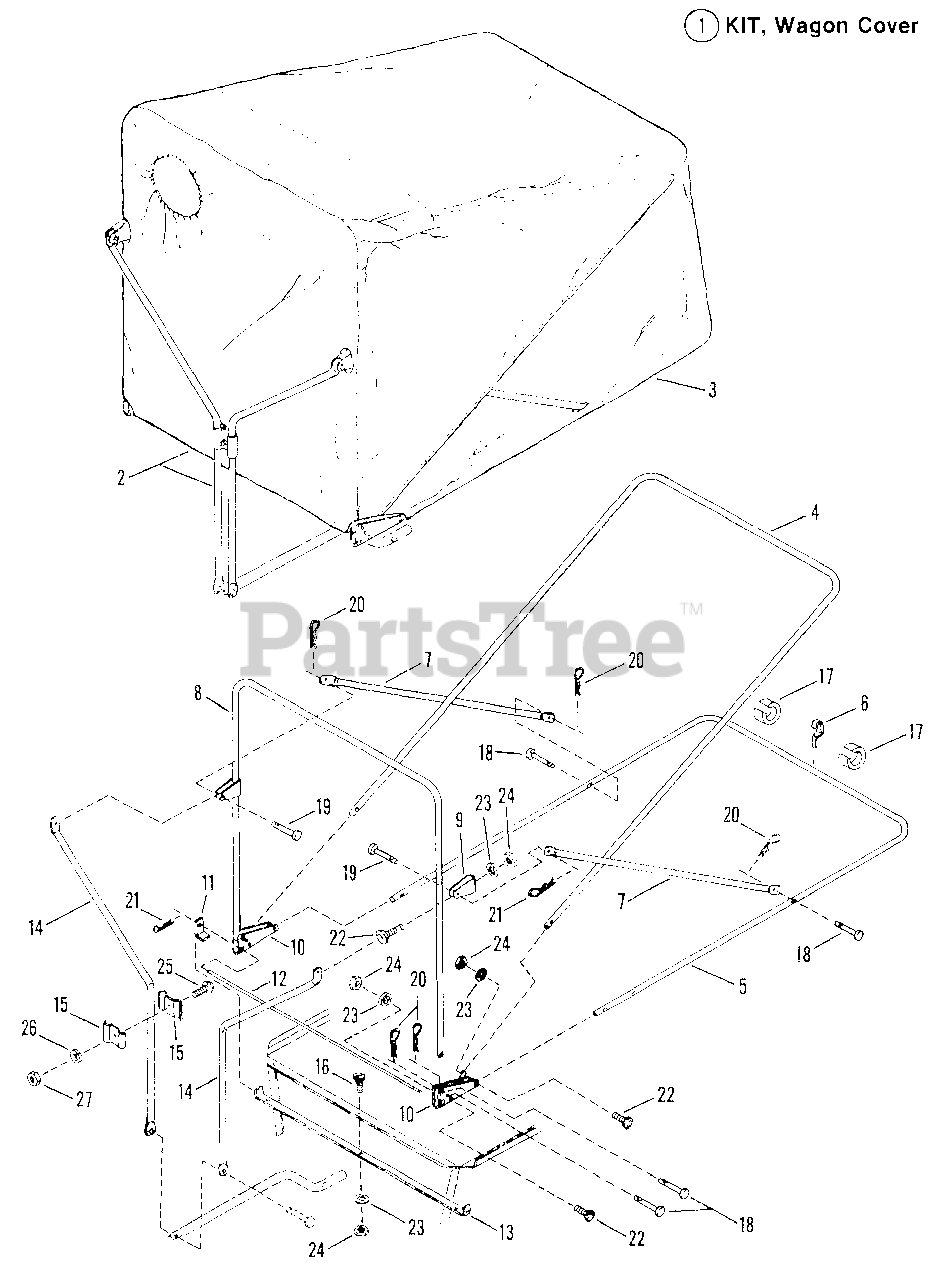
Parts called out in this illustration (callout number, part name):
1	KIT, Wagon Cover
2	FRAME/CANOPY ASSEMBLY
3	CANOPY, Cloth Only
4	FRAME, Center
5	FRAME, Base
6	LOCK, Canopy
7	BRACE, Frame
8	FRAME, Front
9	CLAMP, Rod
10	BRACKET, Corner
11	CLIP, Hinge
12	PIN, hinge
13	Mount, Hinge
14	STRUT, Frame
15	CLAMP, Strut
16	BOLT, 1/4-20x3/4" Carriage
17	BUSHING, Plastic Wear Pads
18	PIN, 1/4x1 1/8" Clevis
19	PIN, 5/16 Clevis
20	PIN, 1/4 Hair
21	PIN, Hair
22	BOLT, 1/4-20x1" Carriage
23	WASHER, 1/4 Internal Tooth Lock
24	NUT, 1/4-20 Hex
25	SCREW, 3/8-24x1" Hex Head Cap
26	WASHER, 3/8 Split Lock
27	NUT, 3/8-24 Hex
